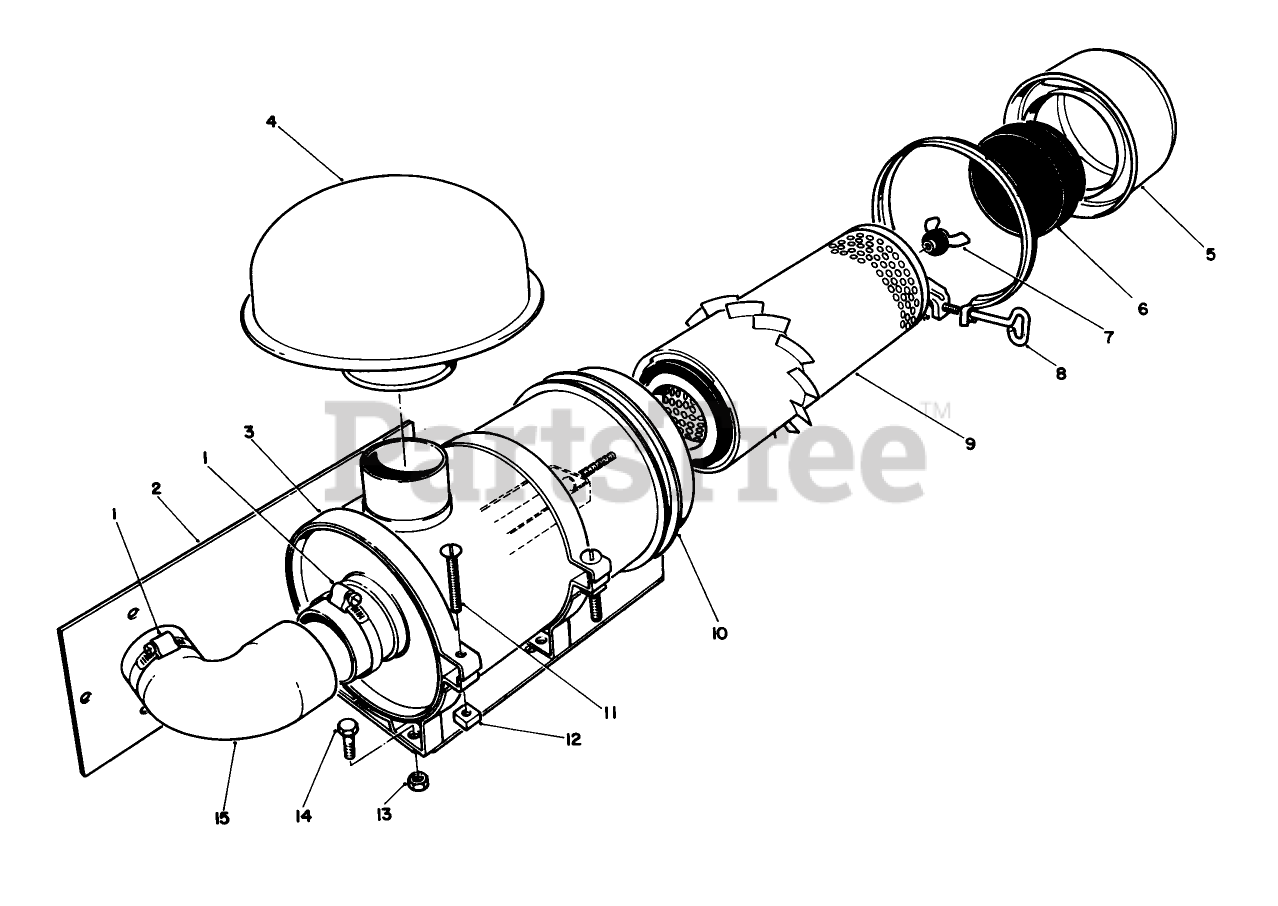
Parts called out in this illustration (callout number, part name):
1	CLAMP-HOSE
1	NUT-HEX
2	BRACKET-MOUNTING
2	WASHER-LOCK, INT
3	MOUNTING BAND ASM
3	BRACKET
4	HOOD-INLET, AIR
5	HR.METER BRKT. *R
10	Body Assembly
11	SCREW
12	NUT-SQUARE
13	NUT-LOCK, NI
14	SCREW-HH
15	HOSE-REMOTE, AIR CLEANER
